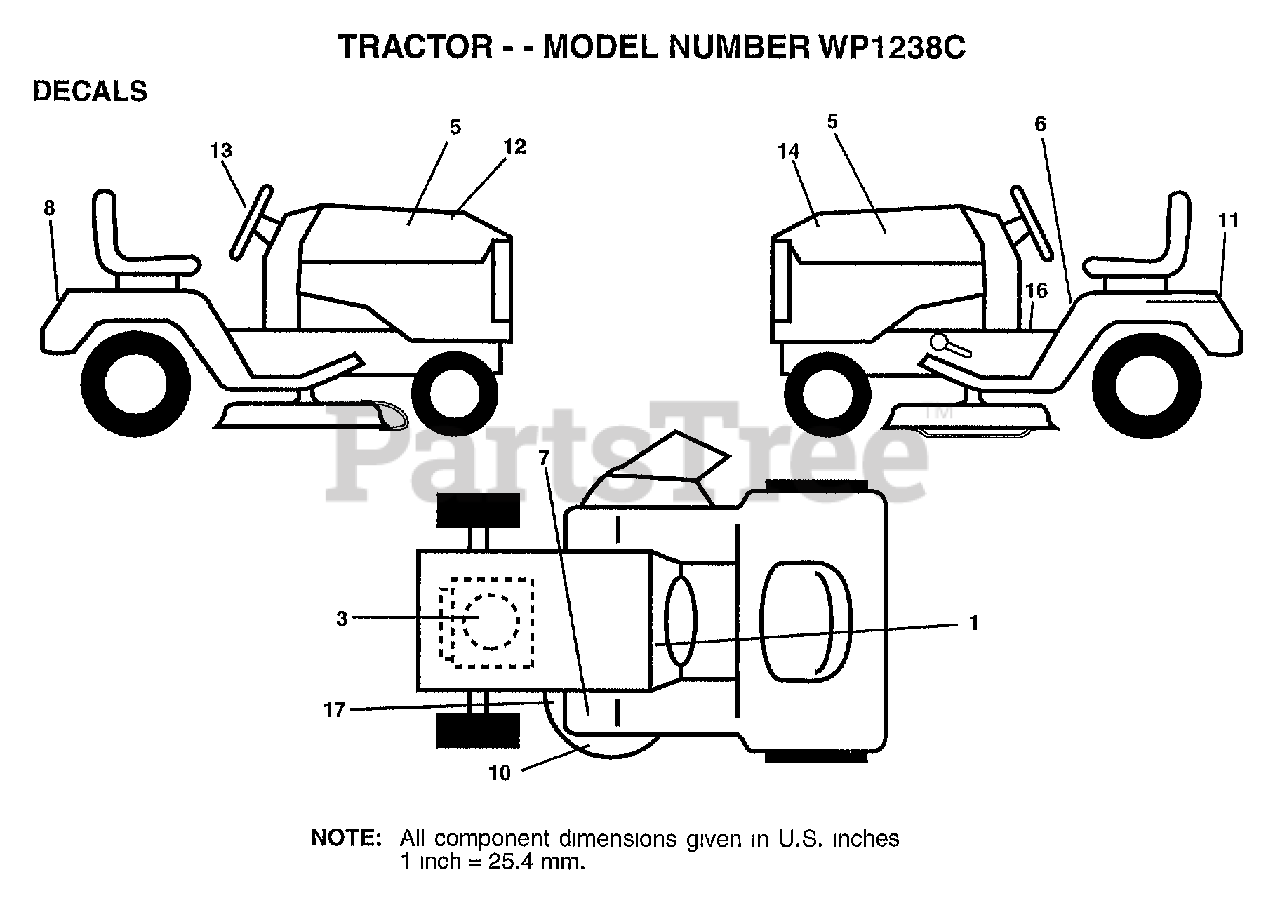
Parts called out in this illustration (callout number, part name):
1	"DECAL-OPER,GEAR D"
3	DECAL, HP ENGINE
5	DECAL.HOOD.LOGO.
6	"DECAL DANGER,FEND"
8	DECAL, FENDER LOGO
11	DECAL.BATRY.3-3908
12	DECAL.HD.RH.WINST
13	DECAL, WHEEL CAP
14	DECAL.HD.LH.WINST
16	DECAL BRAK PARK
17	DECAL
